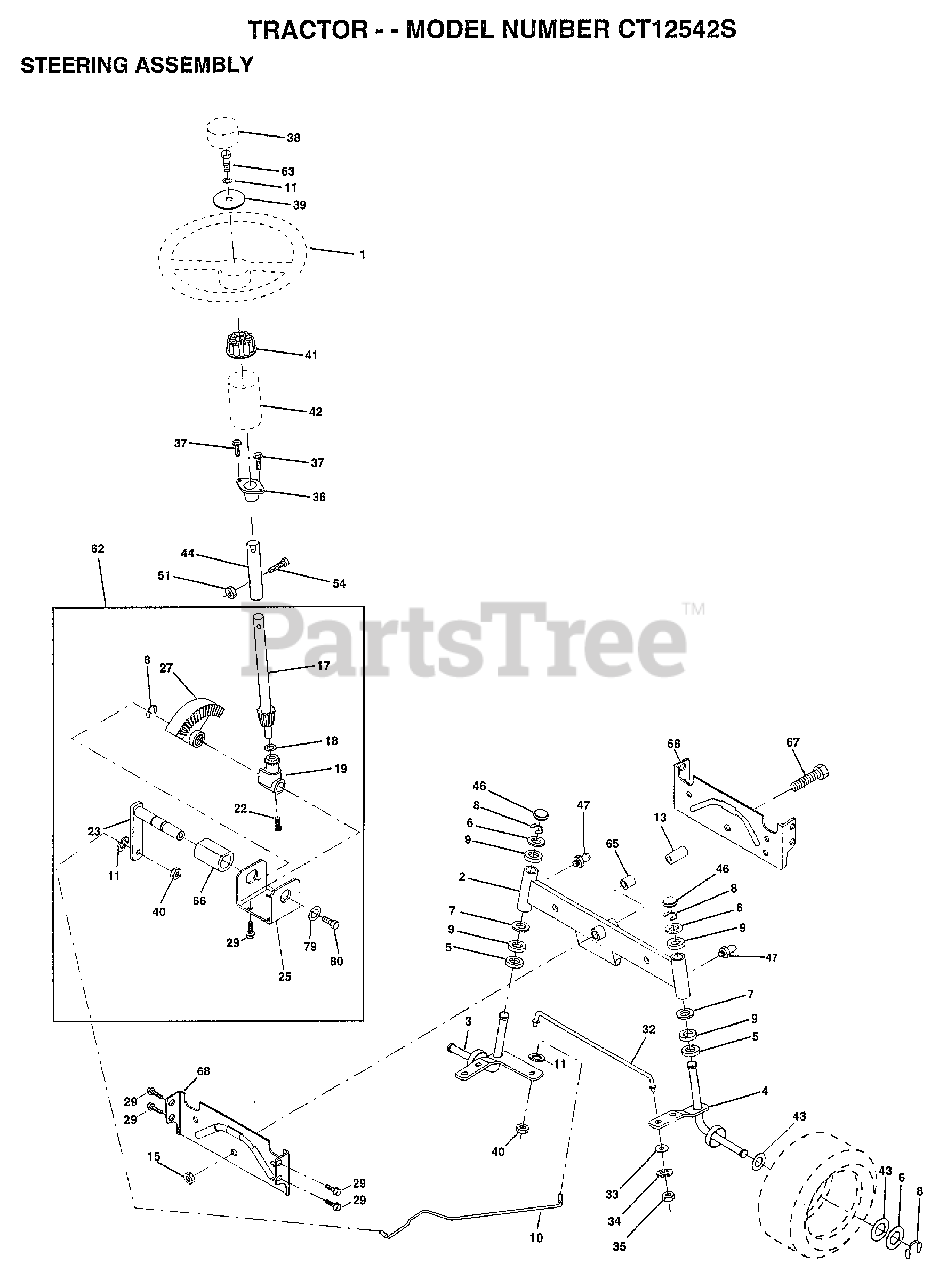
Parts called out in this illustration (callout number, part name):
1	WHEEL STR AYP BLK
2	AXLE ASM
3	SPINDLE.ASM.LH
4	"SPINDLE ASM,RH"
5	WASHER .T
6	WASHER
7	WASHER
8	RING
9	COL. SRTG. BEAR.
10	DRAGLINK-STAMPED
11	LOCKWASHER
13	BEARING AXLE
15	"NUT-LOC,FLANGE LT"
17	SHAFT ASM STEERIN
18	THRUST WASHER
19	SUPPORT.SHAFT.STEER
22	SCREW.HX.WSH.HD
23	SHAFT.ASM.PITMAN
25	BRKT-STEERING
27	GEAR SECTOR
29	SCREW
32	ROD.TIE.19.75
33	WASHER M
34	LOCKWASHER
35	NUT.LOCK.5/16-24
36	BUSHING.STEERING
37	"SCREW-TT,10-32 FL"
38	CAP STEER AYP
39	WASHER T
40	GRIPCO NUT
41	ADAPTER LT
42	BOOT.STEER.PL
43	WASHER
44	EXT SHAFT STEERIN
46	CAP
47	ZERK M
51	NUT
54	BOLT
62	KIT.STEER.ASM
63	BOLT
65	SPACER AXLE
66	"BEARING-ARM,PITMA"
67	BOLT
68	BRACE AXLE
79	WASHER
80	BOLT.HX.NYLON3/8-16X3/
